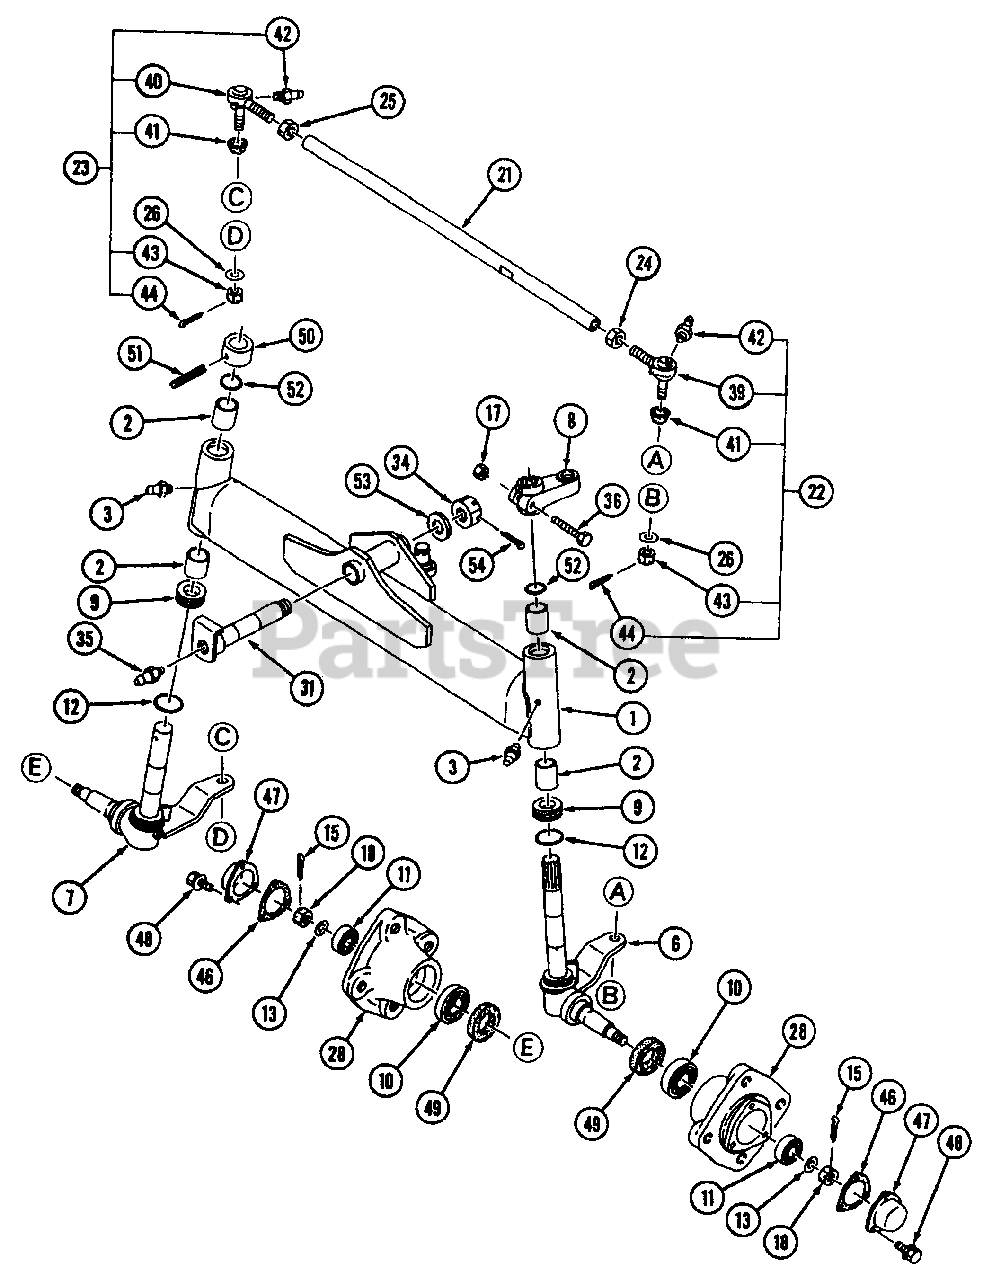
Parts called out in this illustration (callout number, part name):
3	Nipple, Grease
13	Washer
22	End Ass'y - Tie Rod L.H. Side (R.H. Thread)
23	End Ass'y - Tie Rod R.H. Side (L.H. Thread)
24	Nut (R.H. Thread) M17
25	Nut (L.H. Thread) M17
28	Hub, Front Wheel
35	Nipple, Grease
41	Cover, Dust
42	Nipple, Grease
